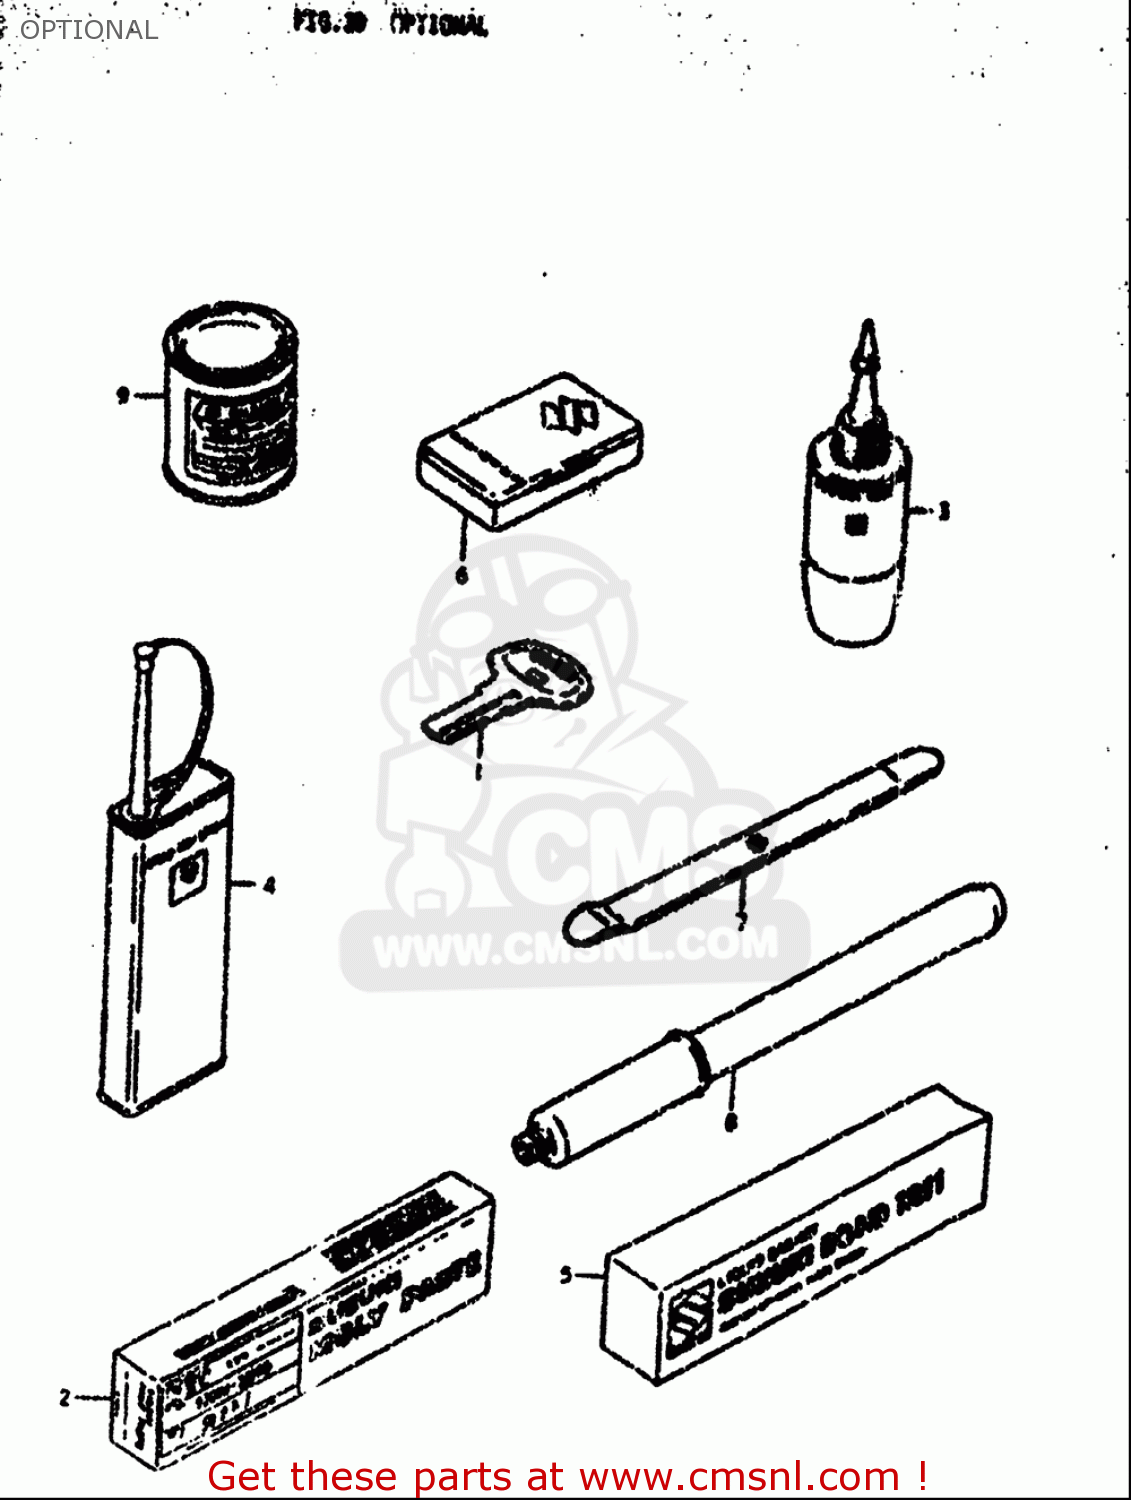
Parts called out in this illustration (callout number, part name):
1	KEY,BLANK
2	SUZUKI MOLY PASTE
3	THREAD LOCK NO.1303B PURPL 50G
4	THREAD LOCK NO.1401 CLEAR 200G
5	LIQUID GASKET 1
7	LEVER,TIRE
